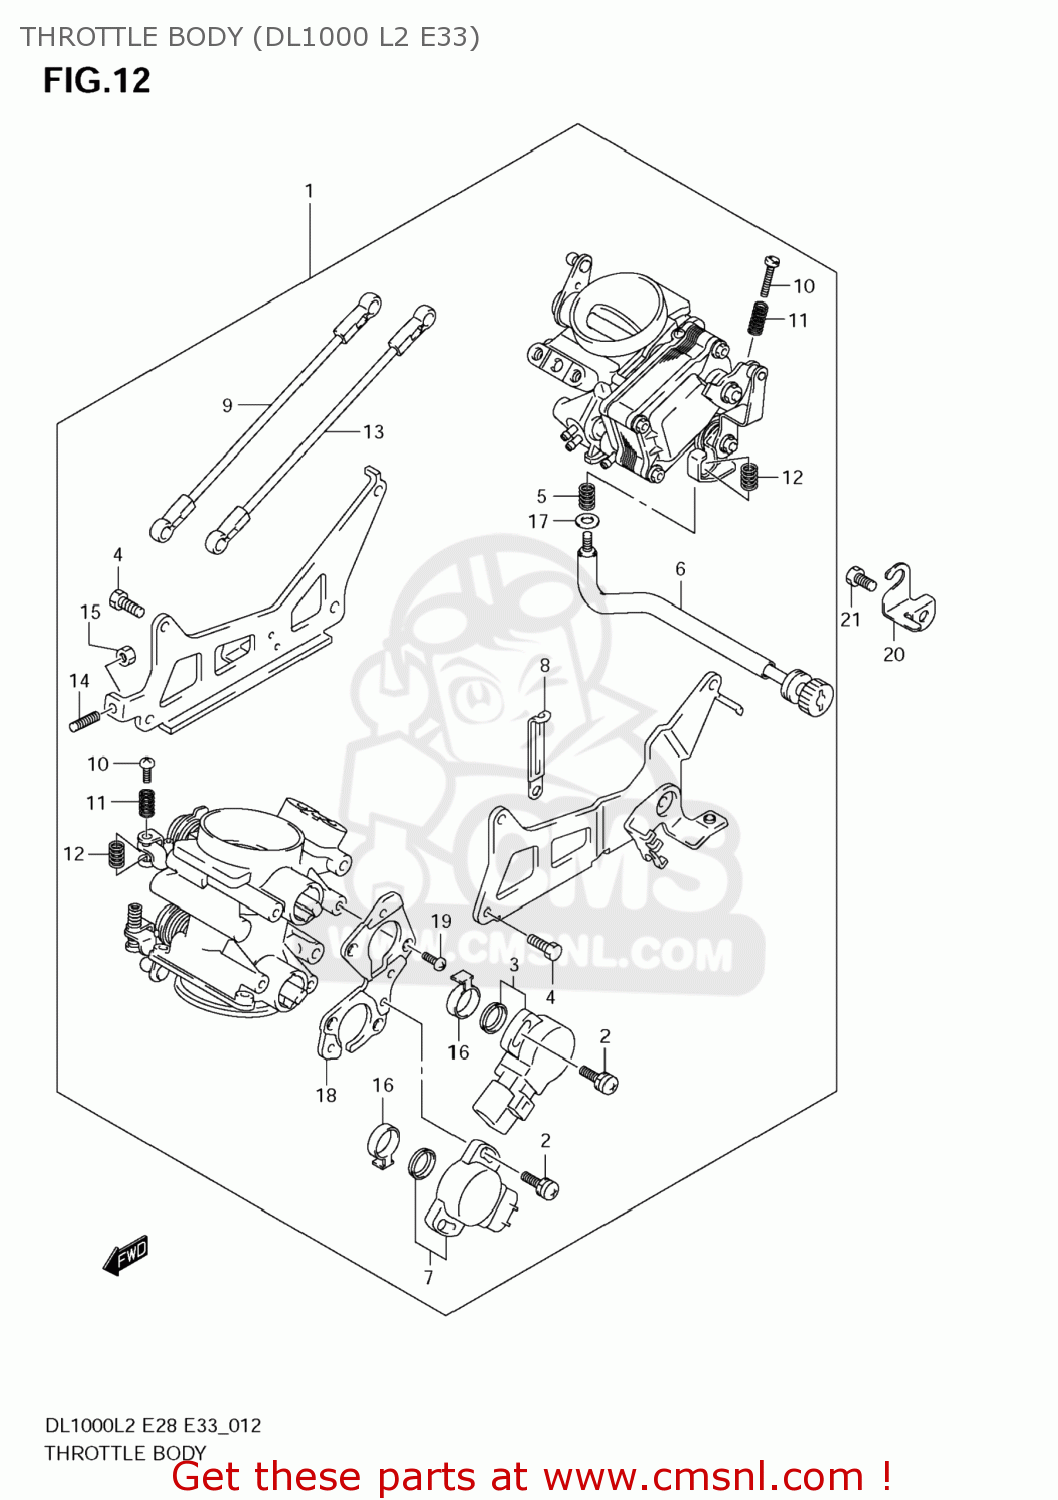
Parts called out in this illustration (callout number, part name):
1	BODY ASSY,THROTTLE
2	SCREW
3	SENSOR ASSY
4	BOLT
5	SPRING
6	SCREW ASSY,ADJUST
7	SENSOR ASSY,THROTTLE
8	CLAMP(L:45)
9	ROD ASSY
10	SCREW
11	SPRING
12	SPRING
13	ROD ASSY
14	SCREW,ADJUST
15	NUT
16	RING
17	WASHER
18	PLATE
19	SCREW
20	PLATE,IDLE ADJUST
21	BOLT
